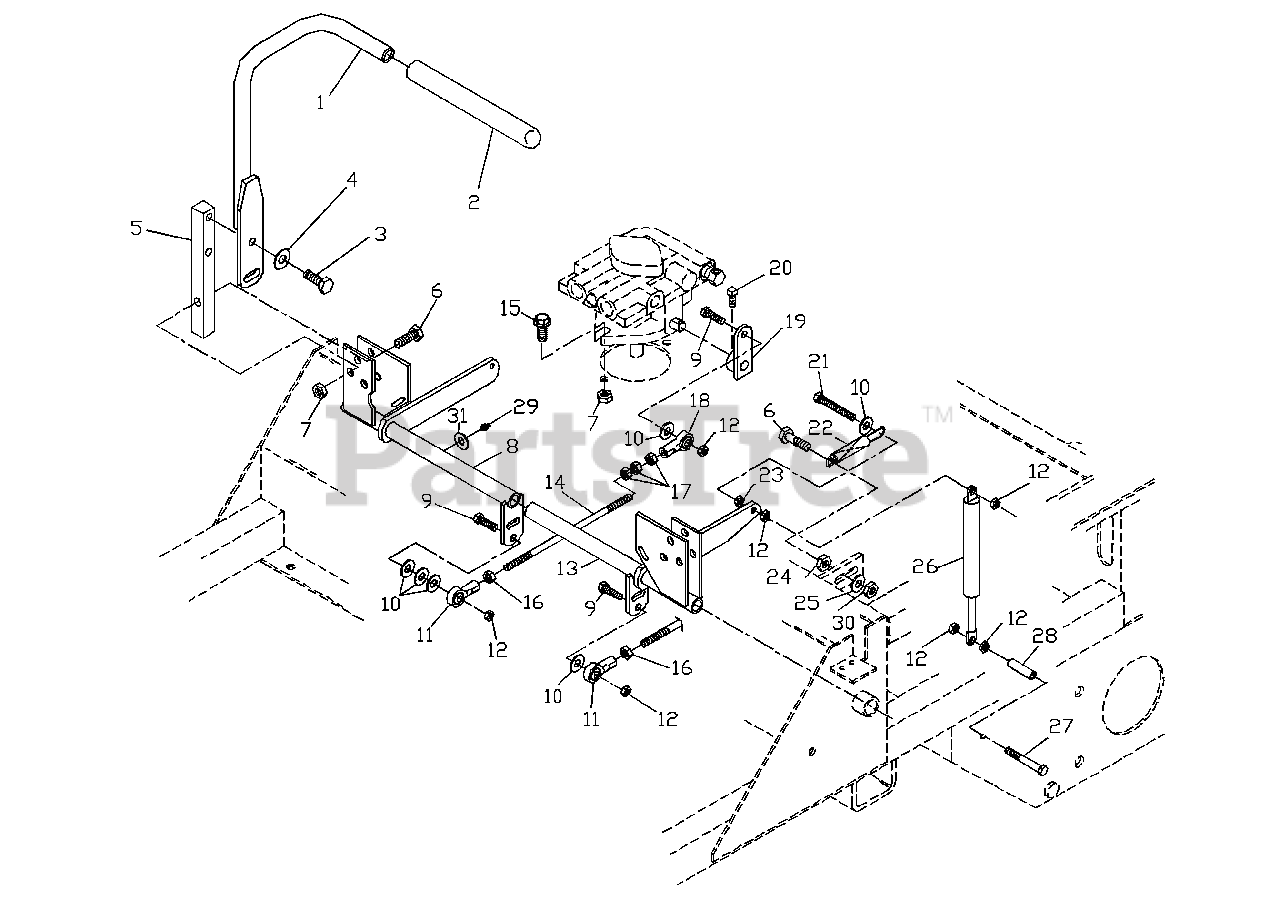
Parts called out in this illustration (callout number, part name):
1	CONTROL LEVER WLDMT.
3	HCS 3/8C X 1
4	3/8 DISC SPRING WASHER
5	CONTROL ARM
6	HCS 3/8C X 1 1/2
7	NUT 3/8C CENTERLOCK
8	CONTROL WELDMENT, RIGHT
9	HCS 5/16C X 1 1/4
10	WASHER 5/16 FLAT
11	BALL JOINT, LEFT HANDED
12	NUT 5/16C CENTERLOCK
13	CONTROL WELDMENT, LEFT
14	PUMP CONTROL LINK
15	HCS 3/8C X 1 SERRATED HEAD
16	NUT 5/16F LEFTHAND
18	BALL JOINT, RIGHTHAND
19	CONTROL ARM, PUMP
20	5/16C X 5/8 SQ. HEAD
21	TAPBOLT 5/16C X 2 1/4
23	5/16C WHIZ NUT
24	3/8C WHIZ NUT
25	WASHER 3/8 FLAT
27	HCS 5/16C X 2 3/4 GRADE 8
29	ZERK
30	NUT 3/8C NYLOC
